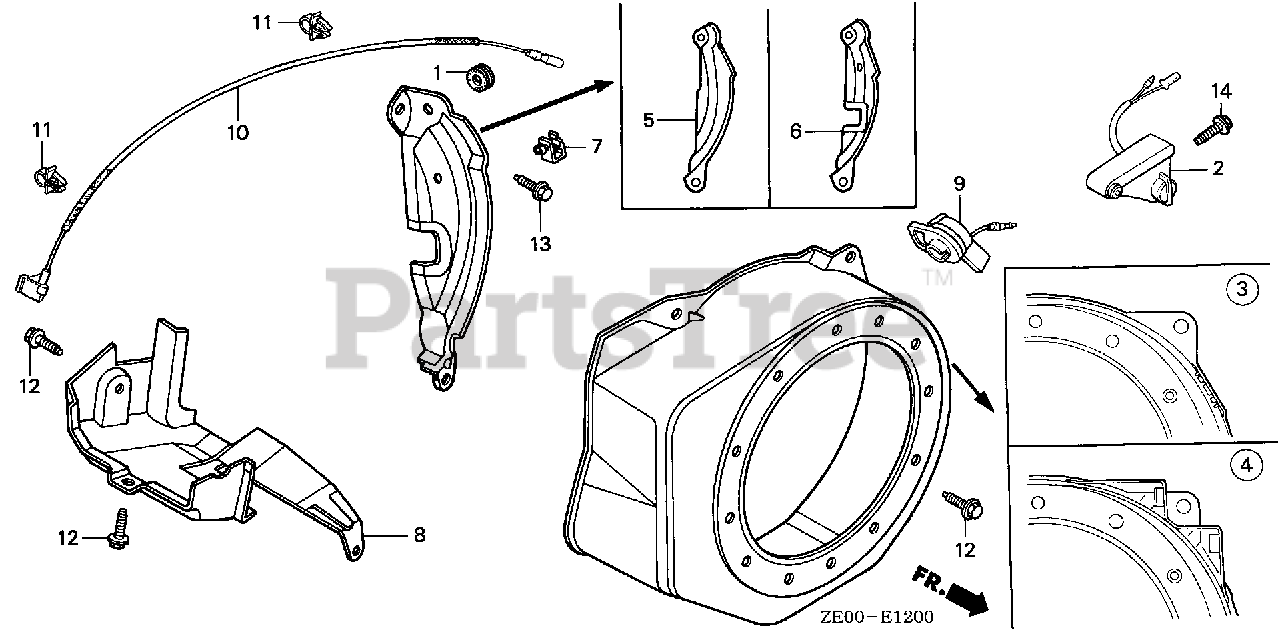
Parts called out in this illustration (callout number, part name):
1	GROMMET, ADJUSTING COVER
2	ALERT UNIT, OIL
4	COVER, FAN *R8* (OIL ALERT) (BRIGHT RED) (NOT AVAILABLE)
5	PLATE, SIDE (OIL ALERT)
7	CLAMP, CORD
8	SHROUD (NOT AVAILABLE)
10	WIRE, STOP SWITCH (370MM)
11	HOLDER, STOP SWITCH WIRE
12	BOLT, FLANGE (6X12) (CT200)
13	BOLT, FLANGE (6X20) (CT200)
14	BOLT, FLANGE (6X8)
